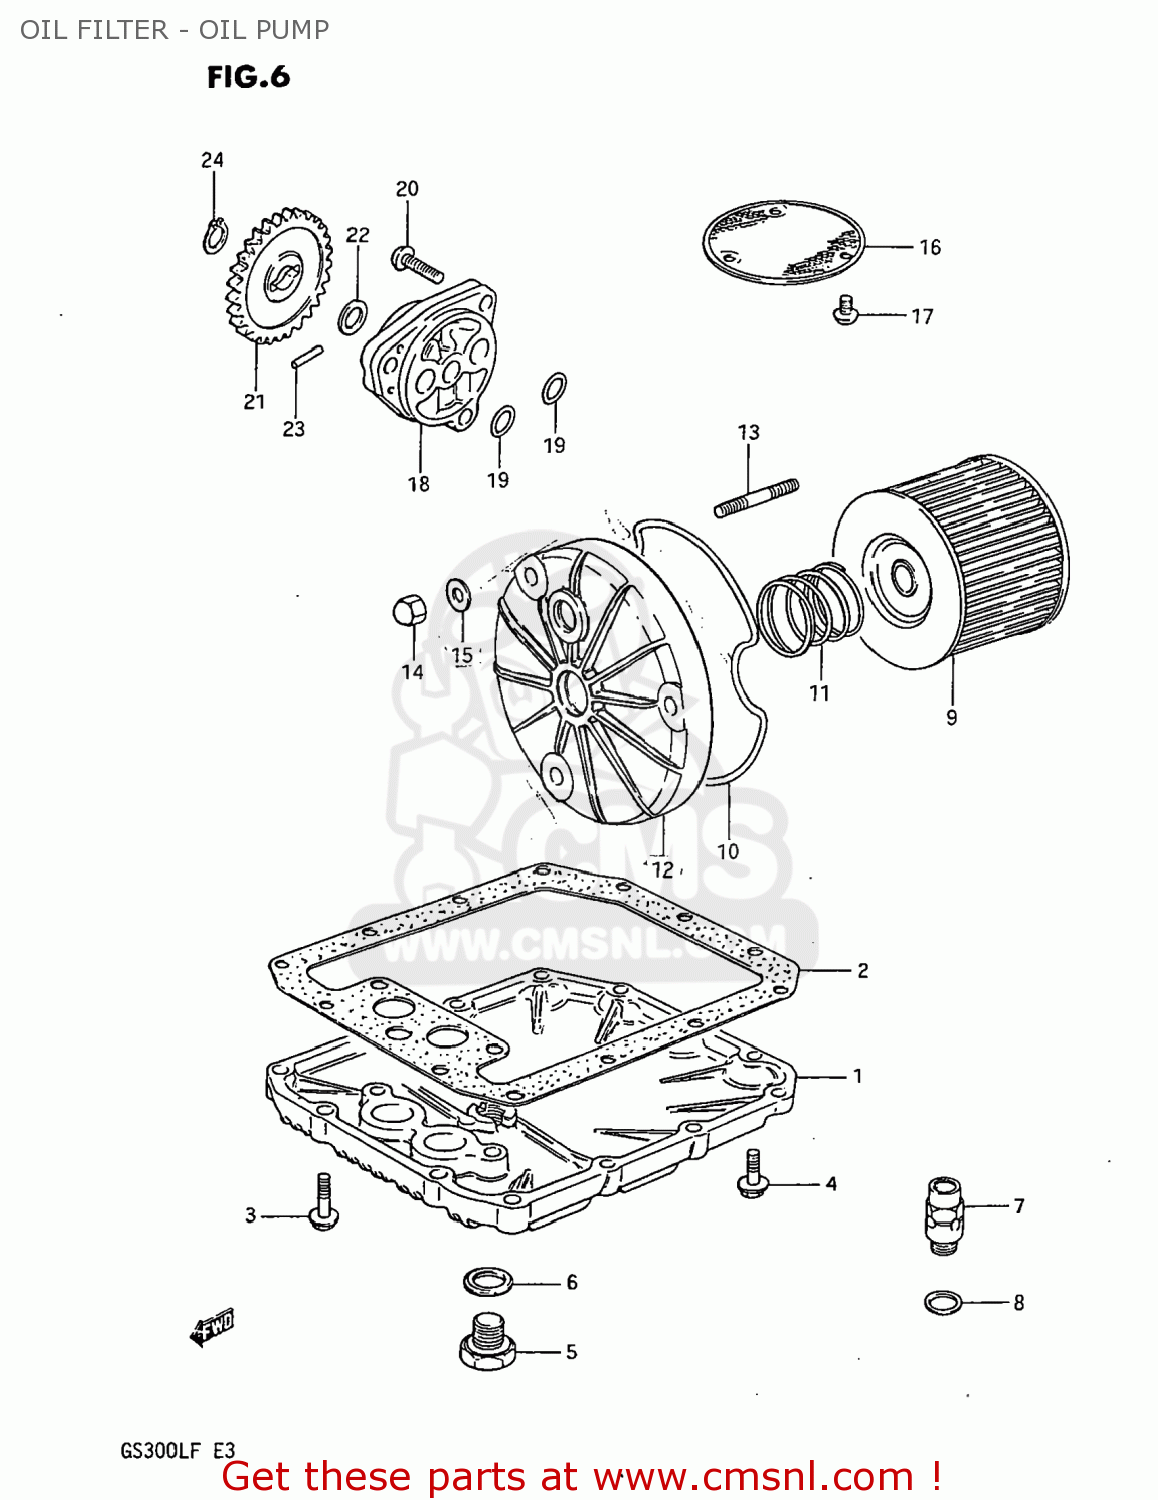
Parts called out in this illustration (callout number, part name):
1	PAN,OIL
2	GASKET,OIL PAN (MCA)
3	BOLT
4	BOLT
5	PLUG
6	GASKET(14X19.2X2) (NAS)
7	VALVE ASSEMBLY,OIL RELIEF
8	WASHER
9	FILTER ASSY,ENGINE OIL
10	O RING,OIL FILTER CHAMBER CAP
11	SPRING
12	CAP,OIL FILTER
13	STUD 6X20
14	NUT 6MM
15	WASHER
16	STRAINER,ENGINE OIL
17	SCREW 6X12
18	PUMP ASSY,ENGINE OIL
19	O RING(D:1.9,ID:13)
20	SCREW
21	GEAR,OIL PUMP DRIVEN
22	SHIM
23	PIN(4X15.8)
24	CIRCLIP
